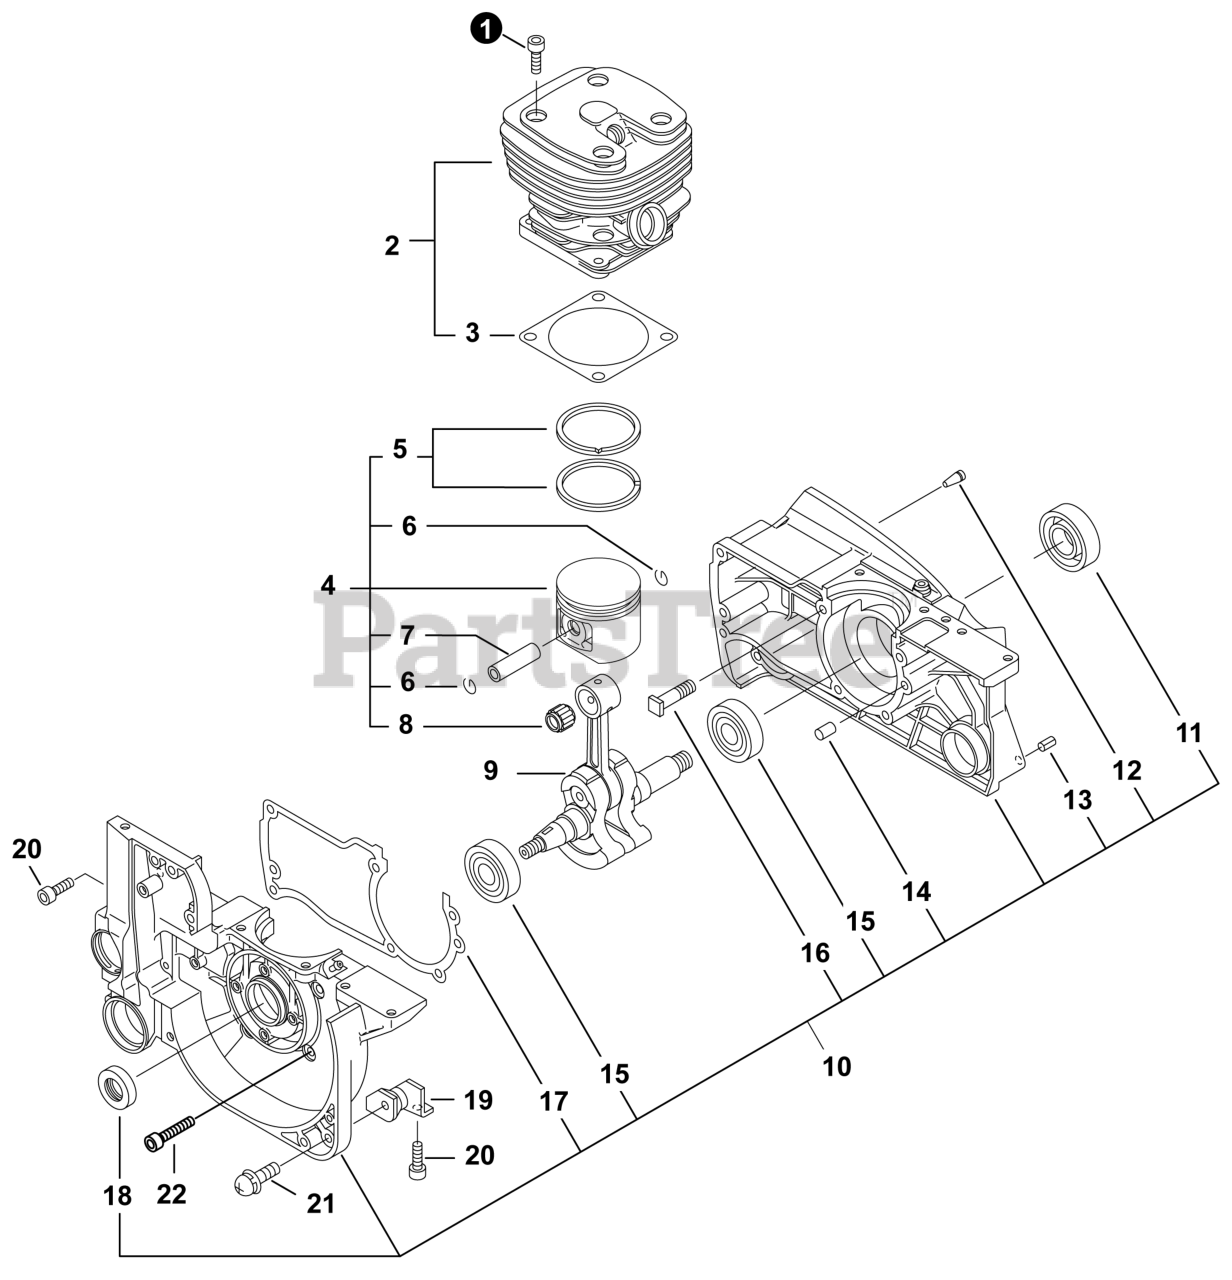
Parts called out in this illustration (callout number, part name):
1	BOLT 6×25
2	CYLINDER ASSY
3	GASKET, CYLINDER
4	PISTON KIT
5	RING, PISTON
6	RING, RETAINING
7	PIN, PISTON
8	BEARING, NEEDLE
9	CRANKSHAFT
10	CRANKCASE KIT - ORANGE
11	SEAL, OIL
12	CHECK VALVE
13	PIN, SPRING 5×10
14	PIN, LOCATING 5×10
15	BEARING, BALL 6203 C3
16	STUD, GUIDE BAR 8
17	GASKET, CRANKCASE
18	SEAL, OIL
20	BOLT 5×20
21	SCREW 5×14
22	BOLT M5×35
